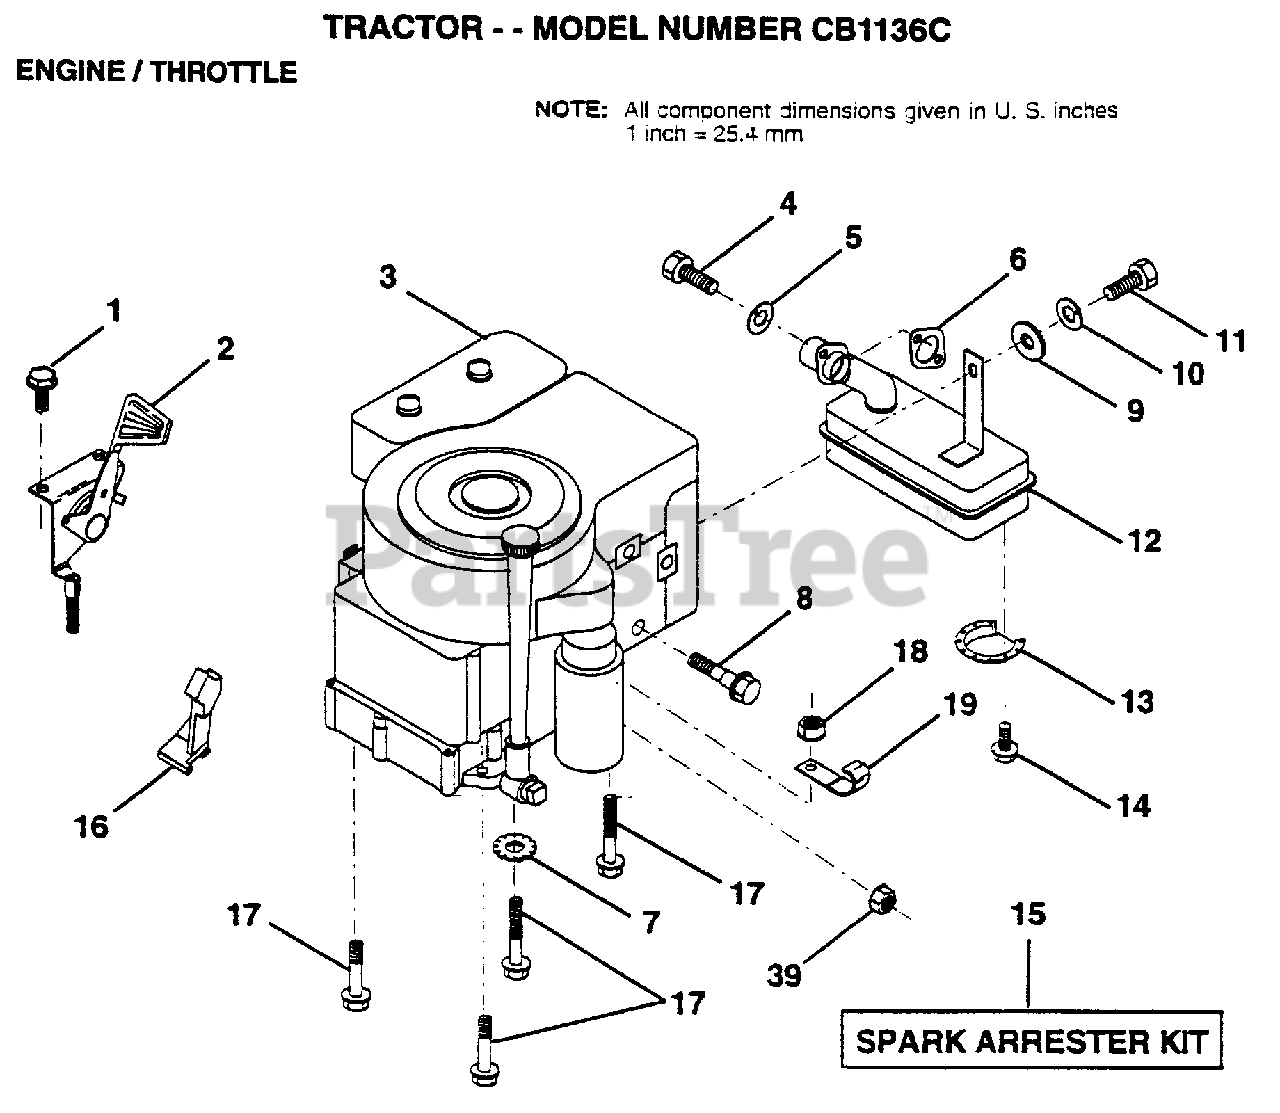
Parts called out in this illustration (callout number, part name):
1	SCREW.1/4-20X1/2
3	ENGINE, B&S, 11HP
4	SCREW
5	LOCKWASHER
7	LOCKWASHER
8	BOLT T
10	LOCKWASHER
11	BOLT
12	MUFFLER
13	DEFLECTOR.222573
16	"STOP,DASH THROTT"
17	SCREW LT
18	NUT
19	CLIP T
39	NUT
